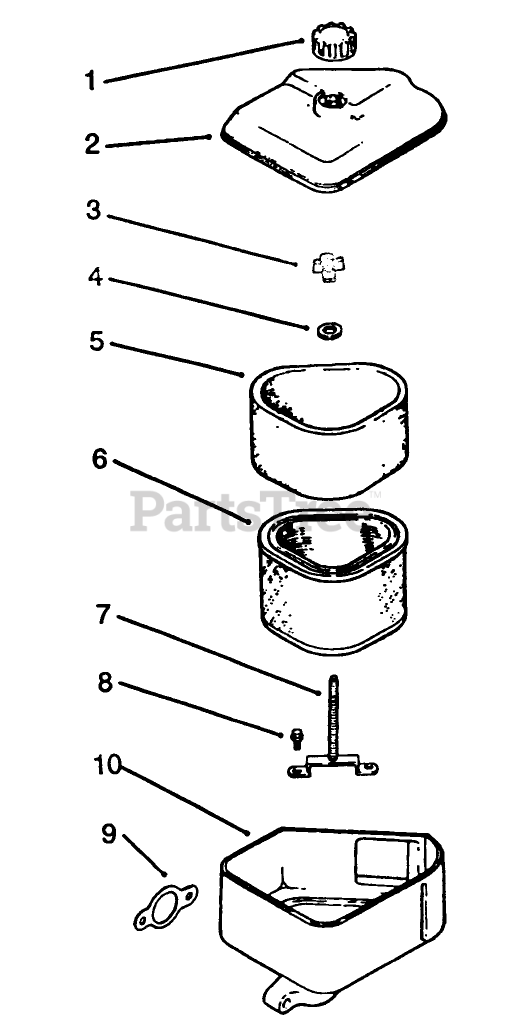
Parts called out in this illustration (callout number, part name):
1	Knob-Air Cleaner Cover (Only On: 72042, 72043, 72062, 72063)
2	Cover-Air Cleaner (Only On: 72042,72043,72062,72063)
3	Nut-Wing
4	Washer
5	Element-Air Cleaner (Only On: 72042, 72043, 72062, 72063)
6	Precleaner-Element (Only On: 72042,72043,72062,72063)
7	Stud-Mounting Plate (Only On: 72042, 72063, 72062, 72043)
8	Screw-Mounting Plate (Only On: 72042, 72043, 72062, 72063)
9	Gasket-Air Cleaner (Only On: 72042, 72043, 72062, 72063)
10	Base-Air Cleaner (Only On: 72042, 72043, 72062, 72063)
